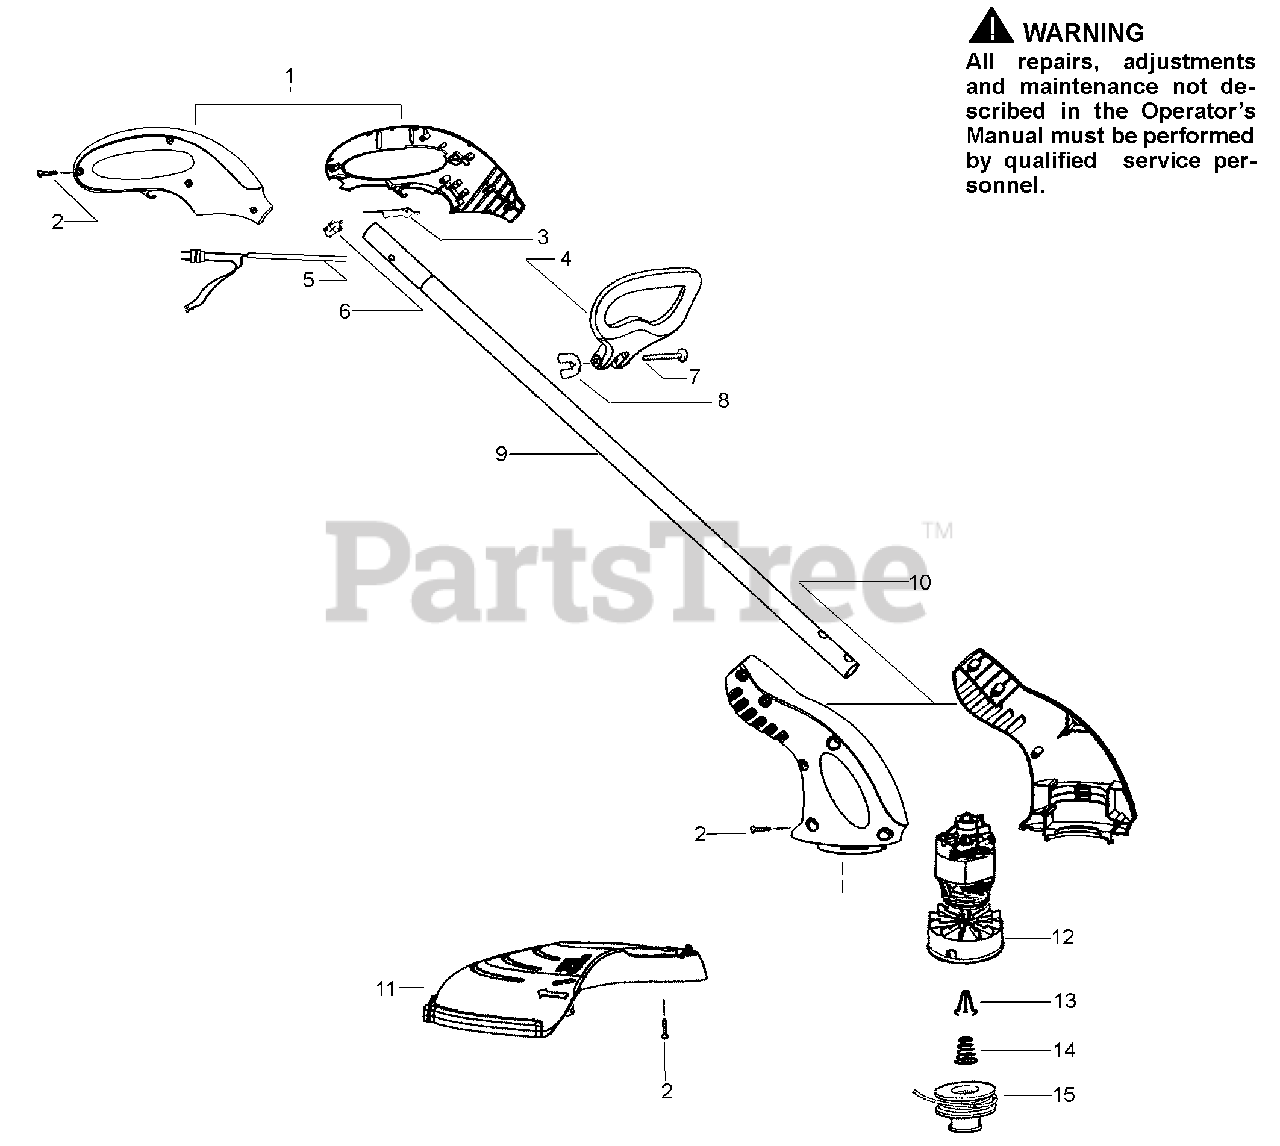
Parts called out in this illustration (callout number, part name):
1	Handle Set
4	Assist Handle
5	Wiring Harness Ass'y.
8	Wingnut
9	Tube Ass'y. w/Decal
10	Housing Set
11	Shield Ass'y.
12	Motor/Hub Ass'y.
13	Retainer-Spool
14	Spring-Return
15	Accy-Spool w/Line
